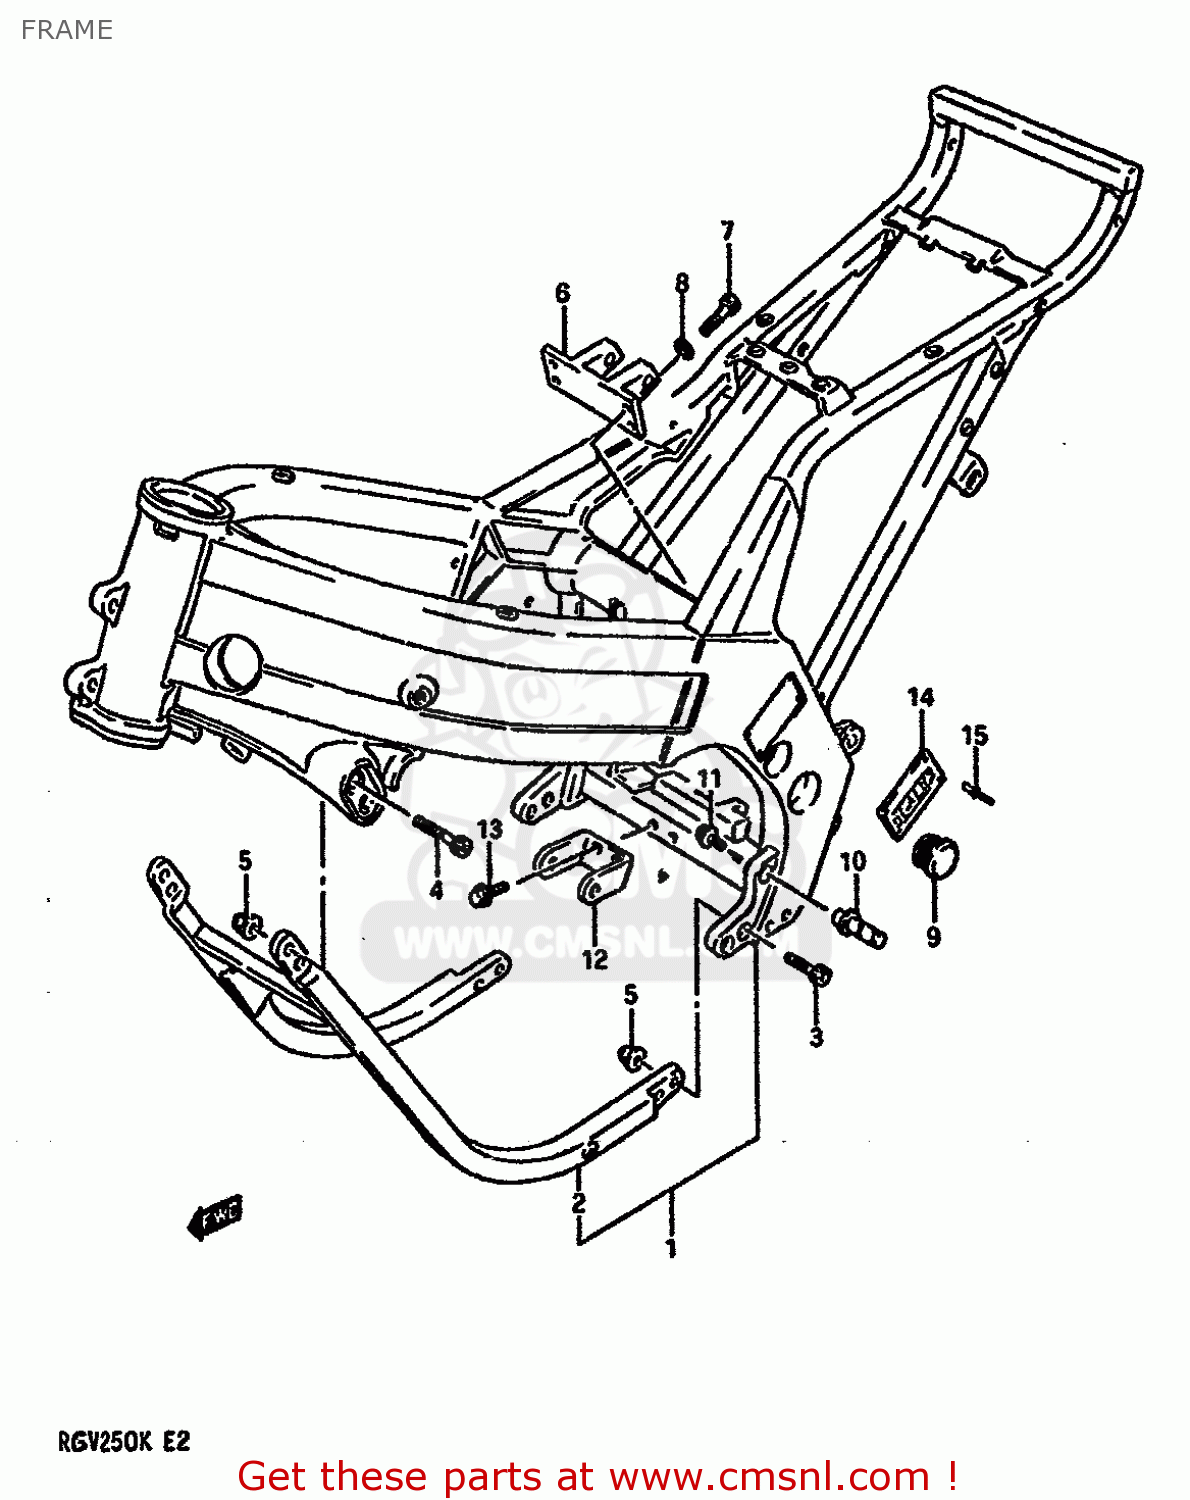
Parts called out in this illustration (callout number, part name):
1	FRAME SET
2	TUBE,FRAME DOWN
3	BOLT, LH
4	BOLT
5	NUT
6	BRACKET,REAR CUSHION UNIT
7	BOLT(8X25)
8	WASHER
9	CAP,BODY FRAME
10	BOSS,GEAR SHIFT
11	BOLT
12	PLATE, ENGINE MOUNTING
13	BOLT 6X16
14	PLATE,ALUMINUM BOX
15	RIVET
